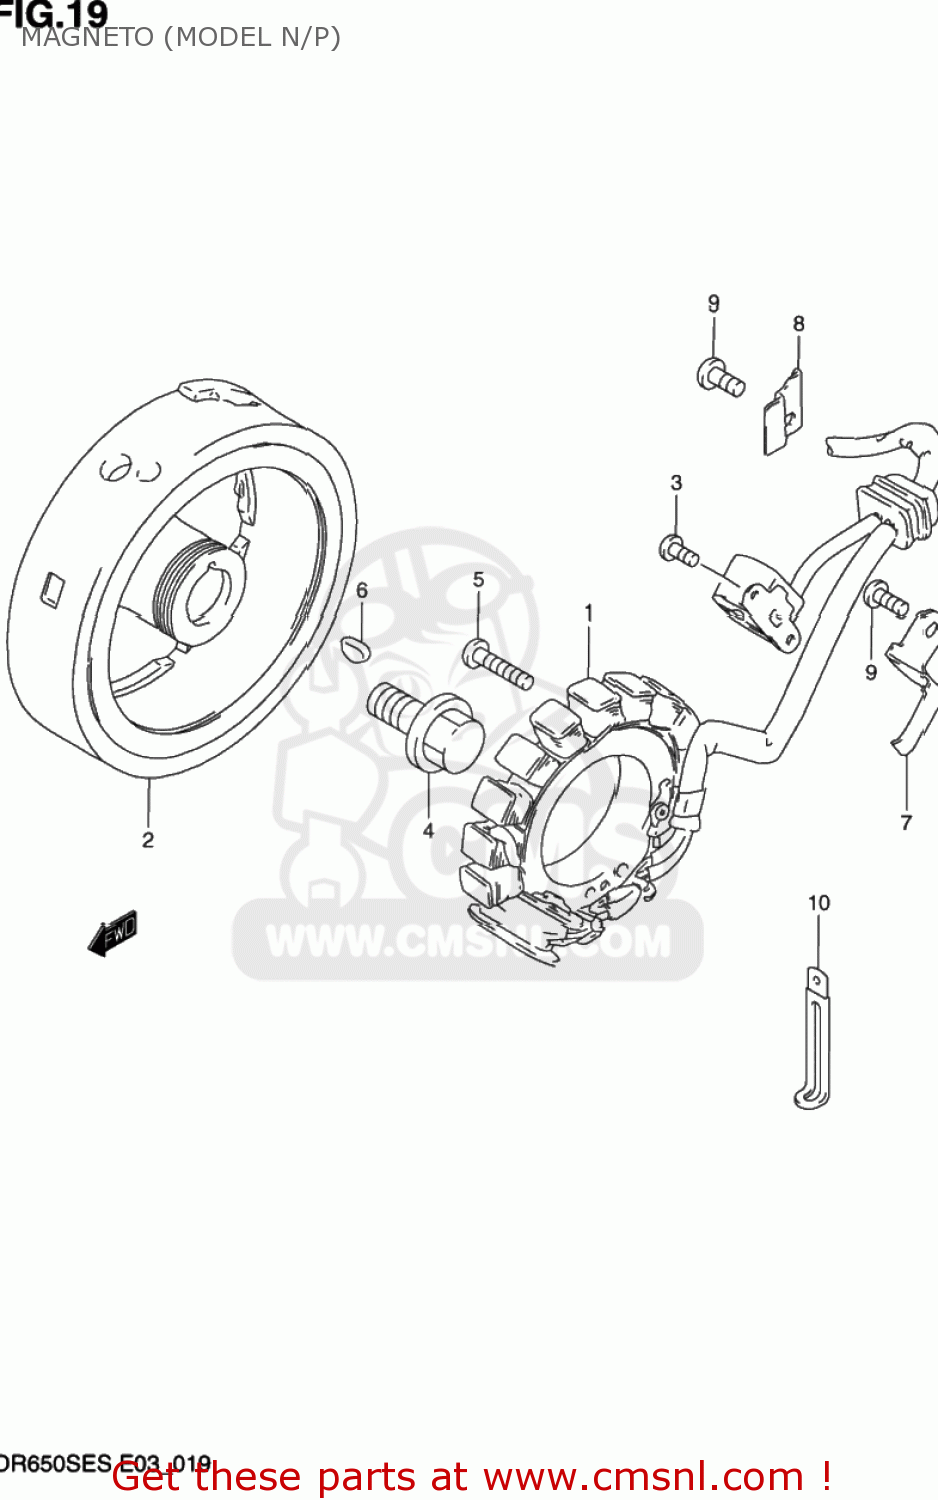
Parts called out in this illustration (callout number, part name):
1	STARTER ASSY
2	ROTOR
3	SCREW
4	BOLT(14X43)
5	SCREW
6	KEY 4MM
7	CLAMP,MAGNETO LEAD WIRE
8	CLAMP,MAGNETO LEAD WIRE
9	SCREW
10	CLAMP
